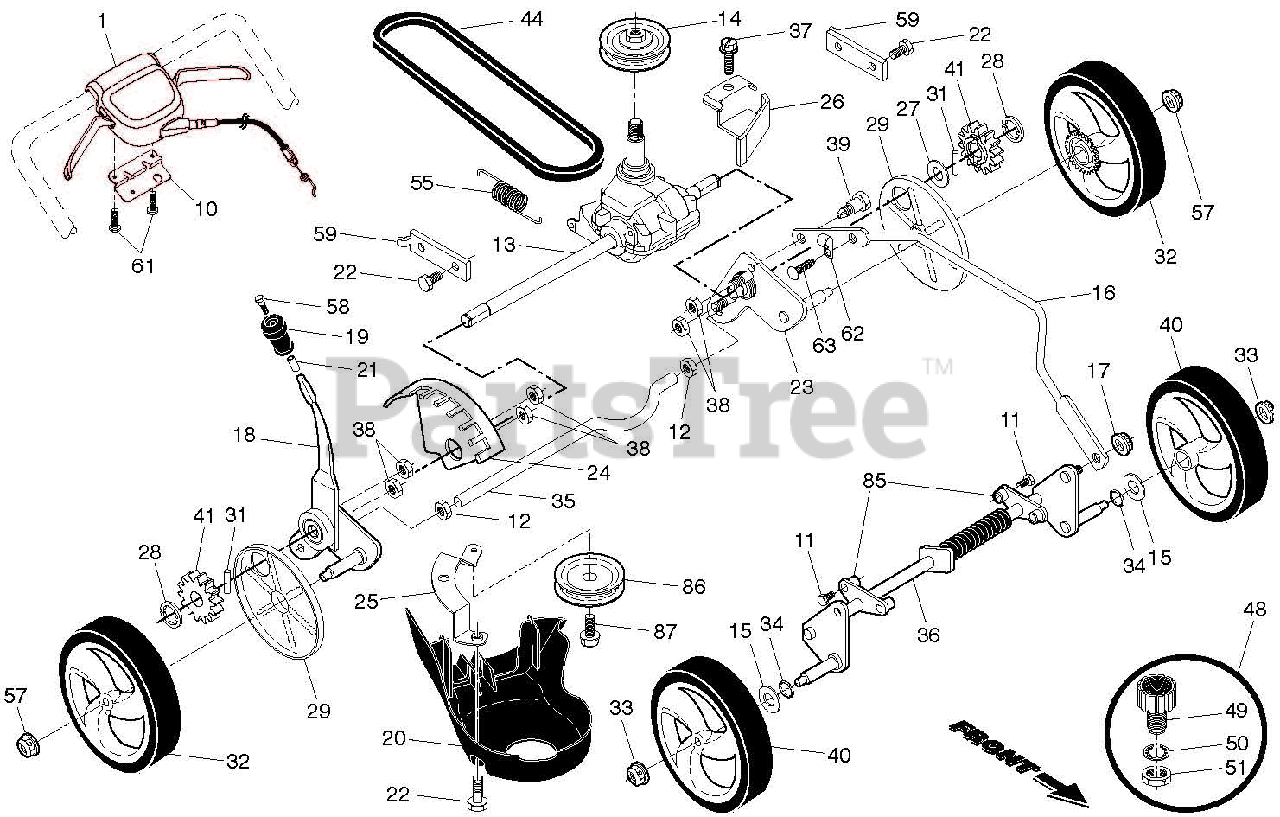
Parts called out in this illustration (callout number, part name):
1	DRIVE CONTROL ASSEMBLY
10	MOUNTING BRCKT, DRIVE CONTROL
11	Screw, Rear Baffle
12	NUT, HEX
13	TRANSMISSION ASM
14	PULLEY, DRIVE
15	Washer, Flat
16	ROD, CONNECTING
17	Nut, Hex
18	KIT, SELECTOR ASSEMBLY
19	KNOB, WHEEL ADJUSTER
20	DEBRIS SHIELD
22	BOLT.5/16-18HEX.WHS.HD.LCKSERR
23	WHEEL AXLE ASSEMBLY, LH
24	BRACKET, HEIGHT ADJUSTMENT
25	MOUNTING BRCKT, DEBRIS SHIELD
26	BELT KEEPER
27	Washer 17/32 x 3/4 x 16 Ga.
29	COVER, DUST, WHEEL
31	Pawl, Drive
32	WHEEL & TIRE ASSEMBLY, REAR
33	Nut, Hex, Flangelock 3/8-16
35	AXLE, REAR
36	AXLE, FRONT
37	SCREW, HI-LO THREAD #12 X 5/8
38	LOCKNUT, HEX 1/4-20
40	WHEEL & TIRE ASSEMBLY, FRONT
44	BELT, DRIVE
48	KIT, WATER WASHOUT ASSEMBLY
49	FITTING, WATER WASHOUT
50	WASHER, LOCK, INTERNAL TOOTH
51	LOCKNUT, HEX, WITH O-RING
55	SPRING, TENSION
57	Flanged Locknut, Hex
58	BOLT, SHOULDER
59	SUPPORT BRACKET
62	Clip, Cable
63	FASTENER, PUSH
85	SUPPORT BRACKET, FRONT AXLE
86	PULLEY, IDLER
